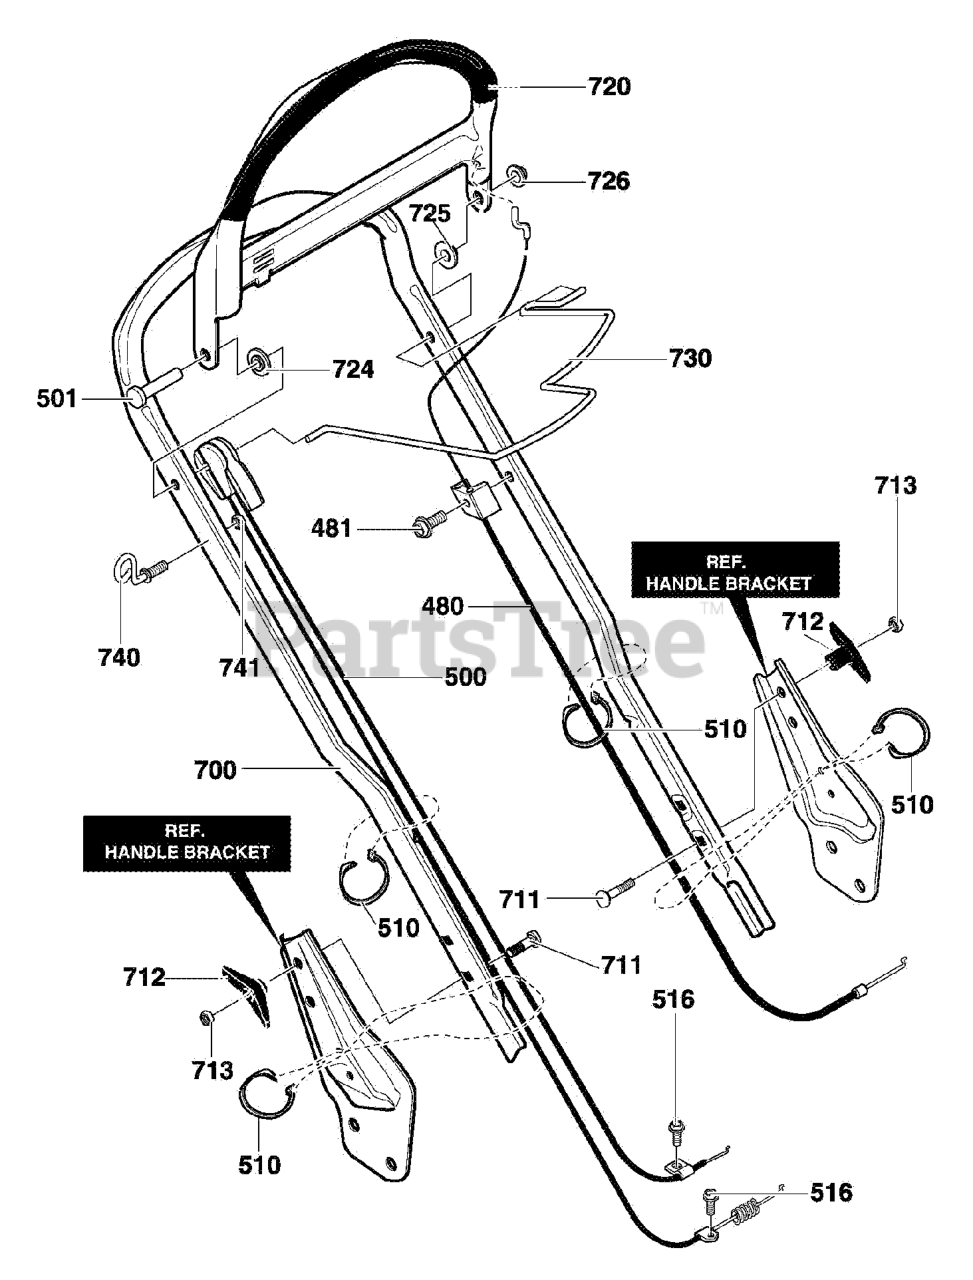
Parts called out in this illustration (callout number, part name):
480	Cable Stop
481	Screw, 10-16x.75
500	Cable, Drive
501	Screw, #10-16x1.38
510	Cable Tie
516	Screw, 10-16x.50
700	Handle
711	Bolt, Carr 5/16-18x2.00
712	Knob, T
713	Nut, 5/16-18
720	Lever, Stop
724	Spacer, Flange
725	Spacer, Flange
726	Retainer Cap
730	Lever, Drive Wire
740	Rope Guide
741	Nut, 1/4-20
